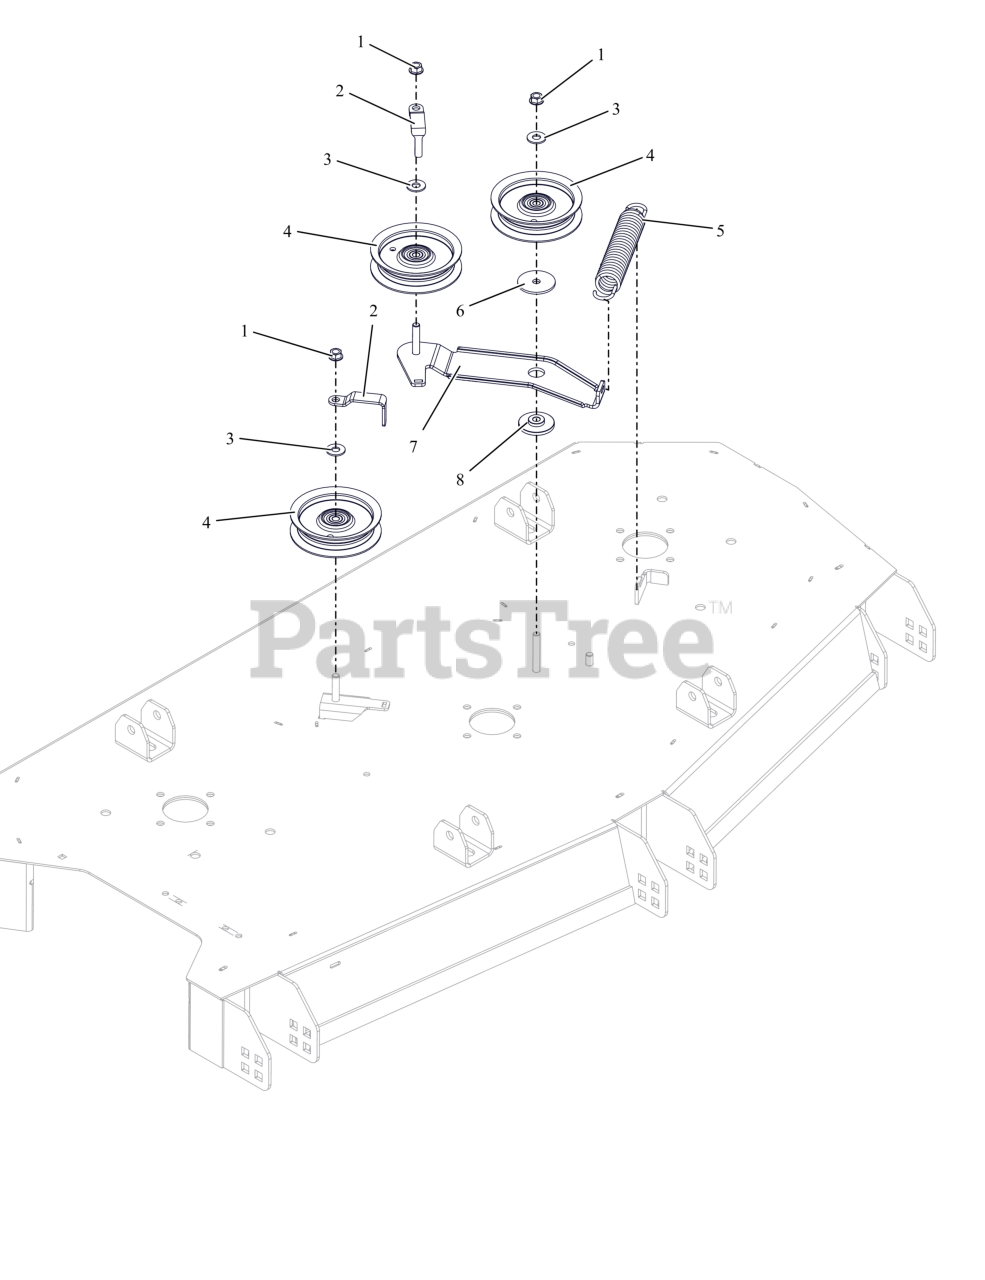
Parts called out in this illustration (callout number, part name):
1	NUT-LK-CTR-FLG .375-16 GF ZCC
2	FINGER, BELT (BLACK)
3	WSHR,FLT .438X1.00X.083 ZCC
4	IDLER, FLAT - 4.06" X .75"
5	SPRG, EXTENSION .170X1.385X6.7
6	WSHR-FL-STL 0.406X2X0.125 ZCC
7	ARM- TENSIONER
8	BSHG-FLG .406X.88X.43X.25
